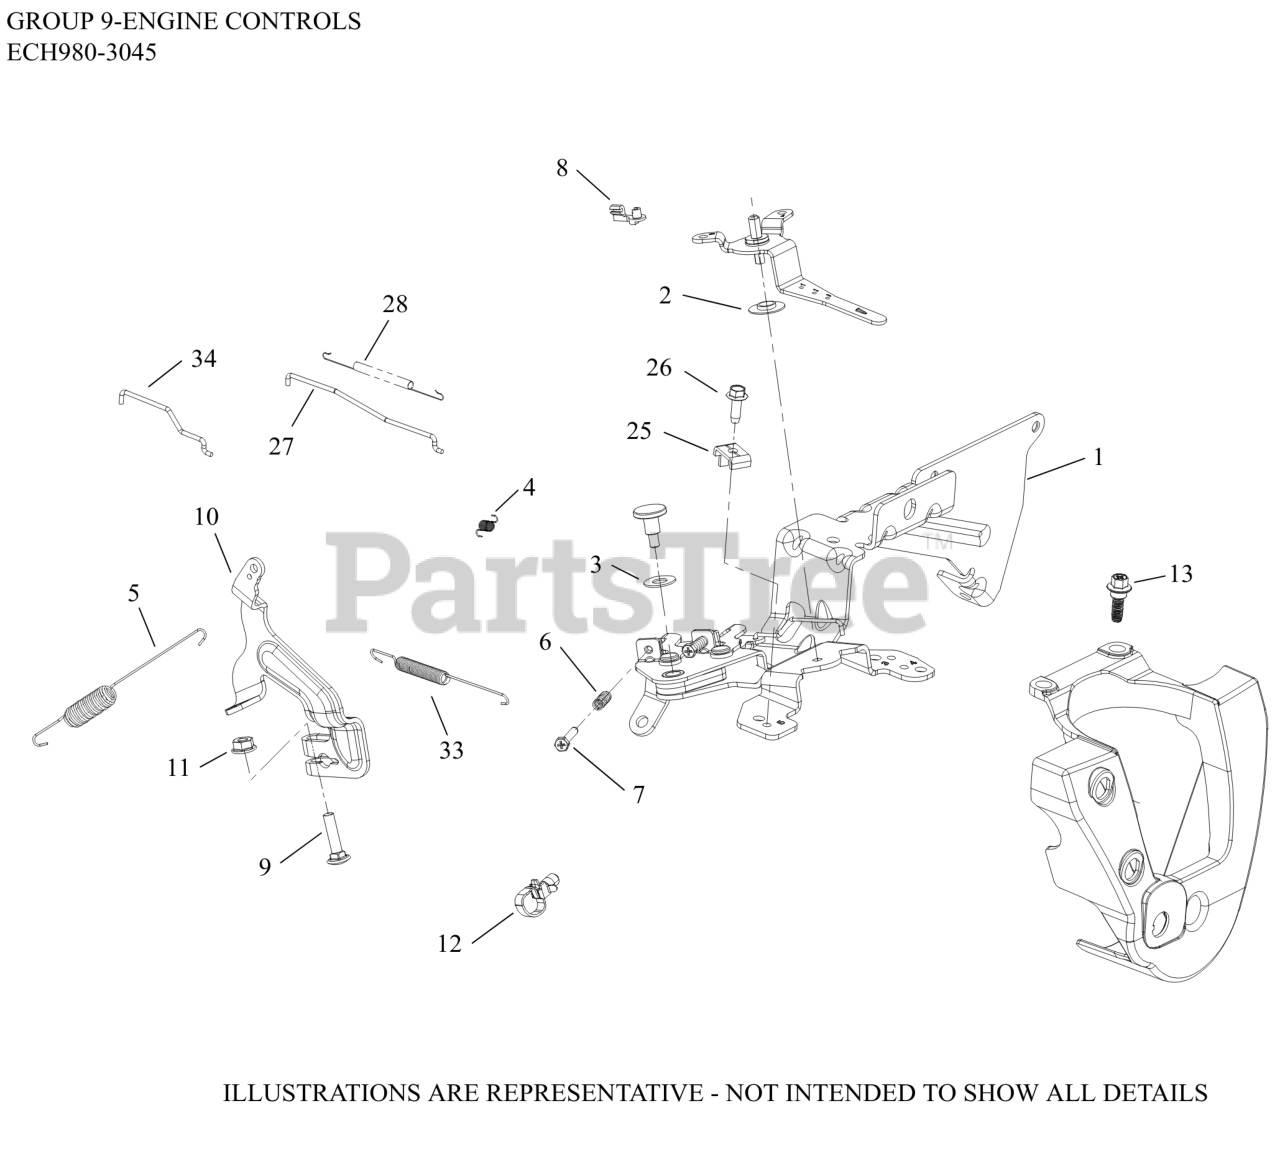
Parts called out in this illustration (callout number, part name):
1	CONTROL ASSEMBLY, SPEED (H/S EFI)
2	WASHER, NYLON SHOULDER
3	WASHER, FLAT 9 MM
4	SPRING, RETURN
5	SPRING, GOVERNOR
6	SPRING, SPEED CONTROL (SHORT)
7	SCREW, PHL THD FRM M4X0.7X25
8	BUSHING, THROTTLE LINKAGE
9	BOLT, RD HD SQ NECK M6X1.0X25
10	KIT, GOVERNOR LEVER
11	NUT, FLG M6X1.0
12	TIE, WIRE
25	CLAMP, CABLE CABLE
26	SCREW, THREAD FORMING
27	LINKAGE, THROTTLE
28	SPRING, LINKAGE
33	SPRING, GOV (HORZ IDLE 1626-1800)
34	LINKAGE, CONTROL LEVER
